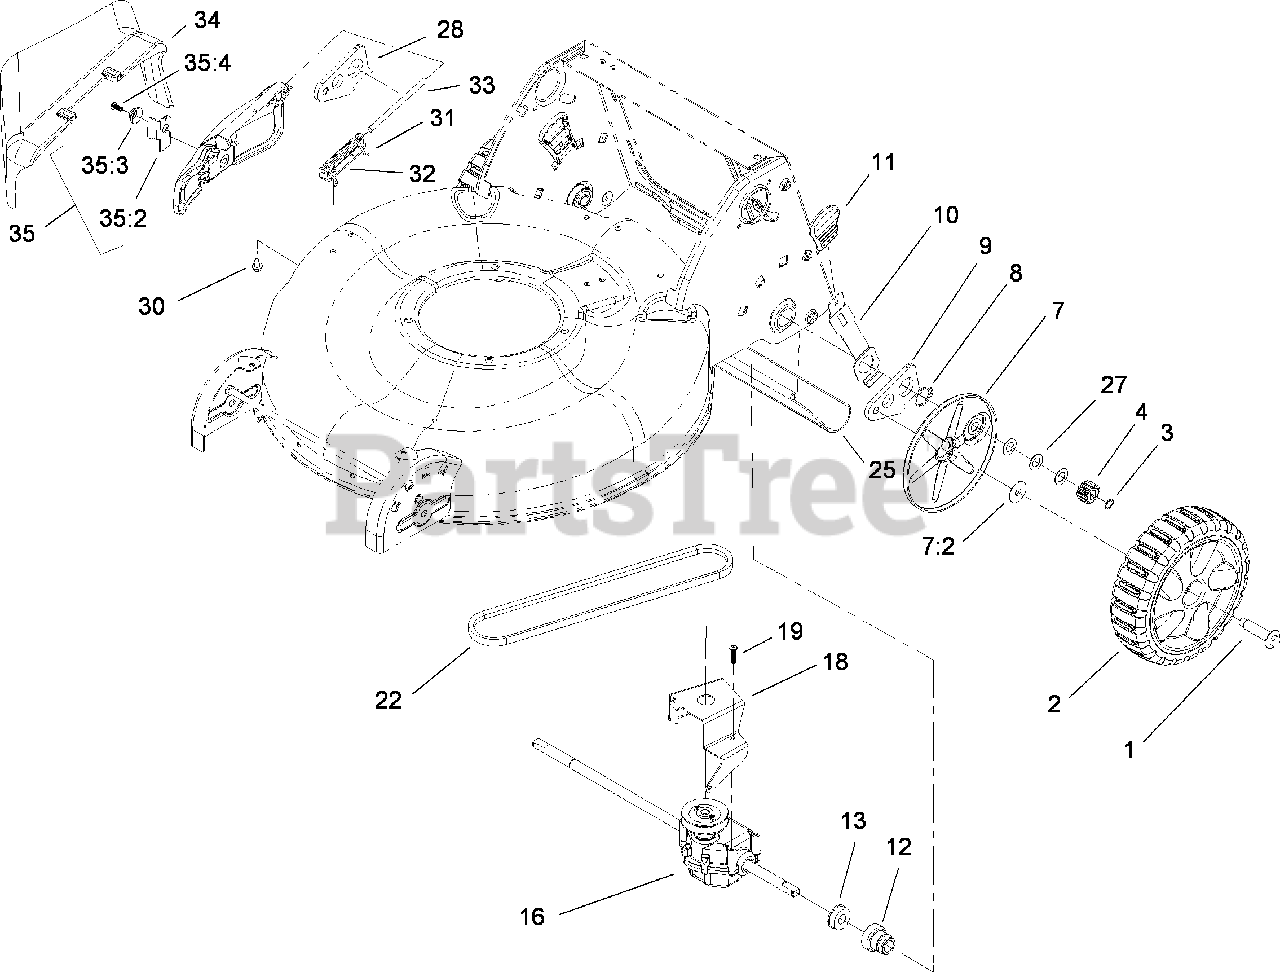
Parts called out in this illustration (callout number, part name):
1	BOLT-SHOULDER
2	REAR WHEEL ASM
3	RING-RETAINING
4	PINION
7	WHEEL COVER ASM
7:2	WASHER-STEPPED
8	RING-RETAINING
9	ARM-REAR PIVOT, LH
10	ARM-SPRING, REAR
12	RETAINER-BEARING, HOC
13	BEARING-BALL
16	TRANSMISSION ASM
18	BRACKET-TRANSMISSION
19	SCREW-PLASTITE
25	SHIELD-TRAILING
27	WASHER-PLAIN
28	ARM-REAR PIVOT, RH
30	SCREW-HWH
31	SPRING-TORSION
32	BRACKET-COVER
33	ROD-COVER
34	CHUTE-DISCHARGE, SIDE
35	DISCHARGE DOOR ASM
35:2	LATCH-DOOR
35:3	CAP-DOOR
35:4	SCREW-PLASTITE
